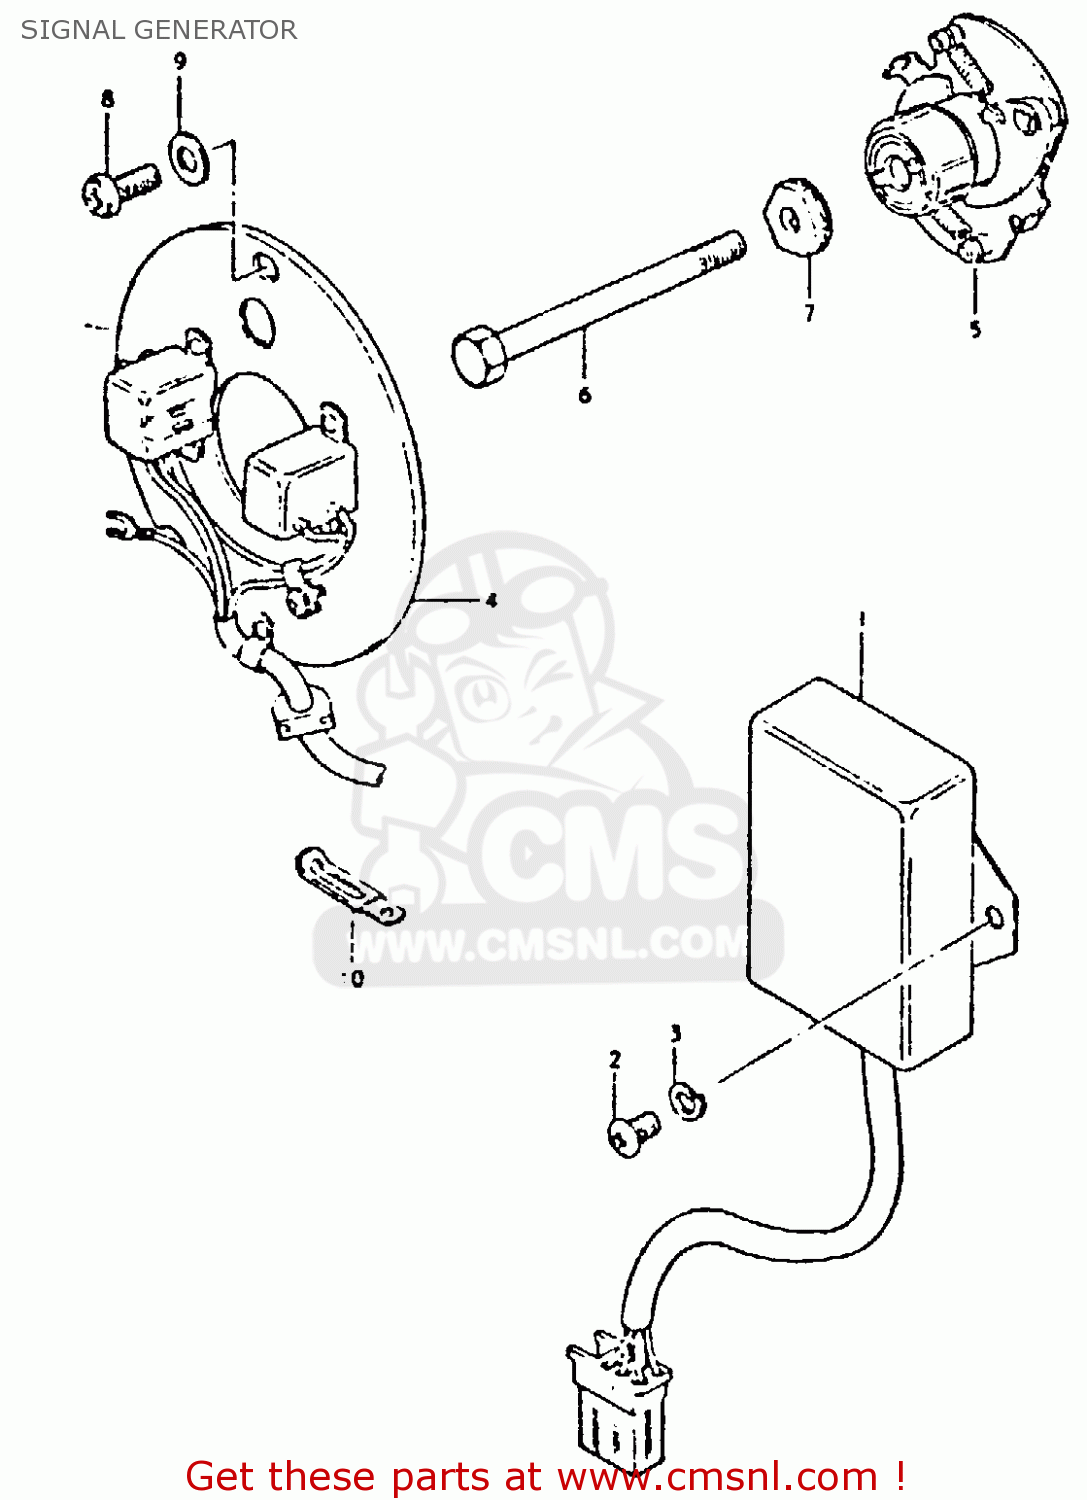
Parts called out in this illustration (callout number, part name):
1	CDI UNIT KOKUSAN
2	SCREW
3	LOCK WASHER
4	SIGNAL GENERATOR ASSEMBLY
5	GOVERNOR ASSEMBLY
6	BOLT 6X60
7	WASHER,CONTACT BREAKER
8	SCREW(5X12)
9	WASHER
10	CLAMP L:35
